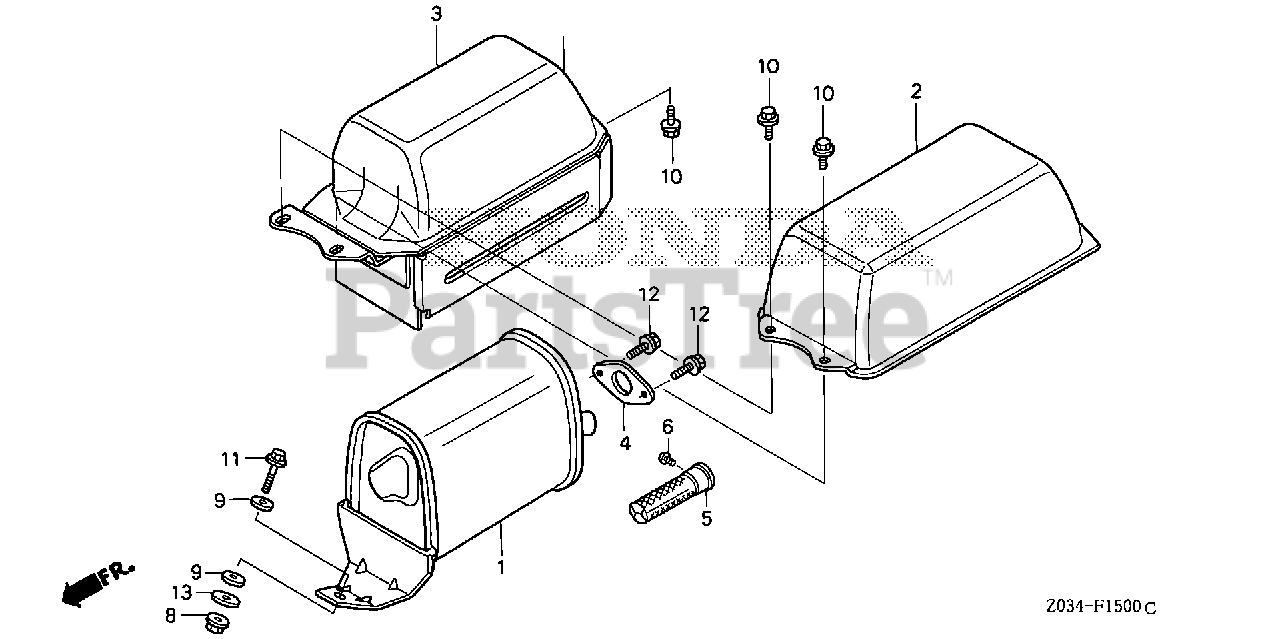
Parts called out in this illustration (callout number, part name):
1	MUFFLER (A)
2	PROTECTOR, MUFFLER (UPPER) *NH105* (MAT BLACK)
3	PROTECTOR, MUFFLER (INNER)
4	GASKET, EX. PIPE
5	ARRESTER, SPARK
6	SCREW, TAPPING (4X6)
8	NUT, FLANGE (6MM)
9	WASHER, PLAIN (6MM)
10	BOLT, FLANGE (6X12)
11	BOLT, FLANGE (6X30)
12	BOLT, FLANGE (8X20)
13	WASHER, WHEEL (6MM)
